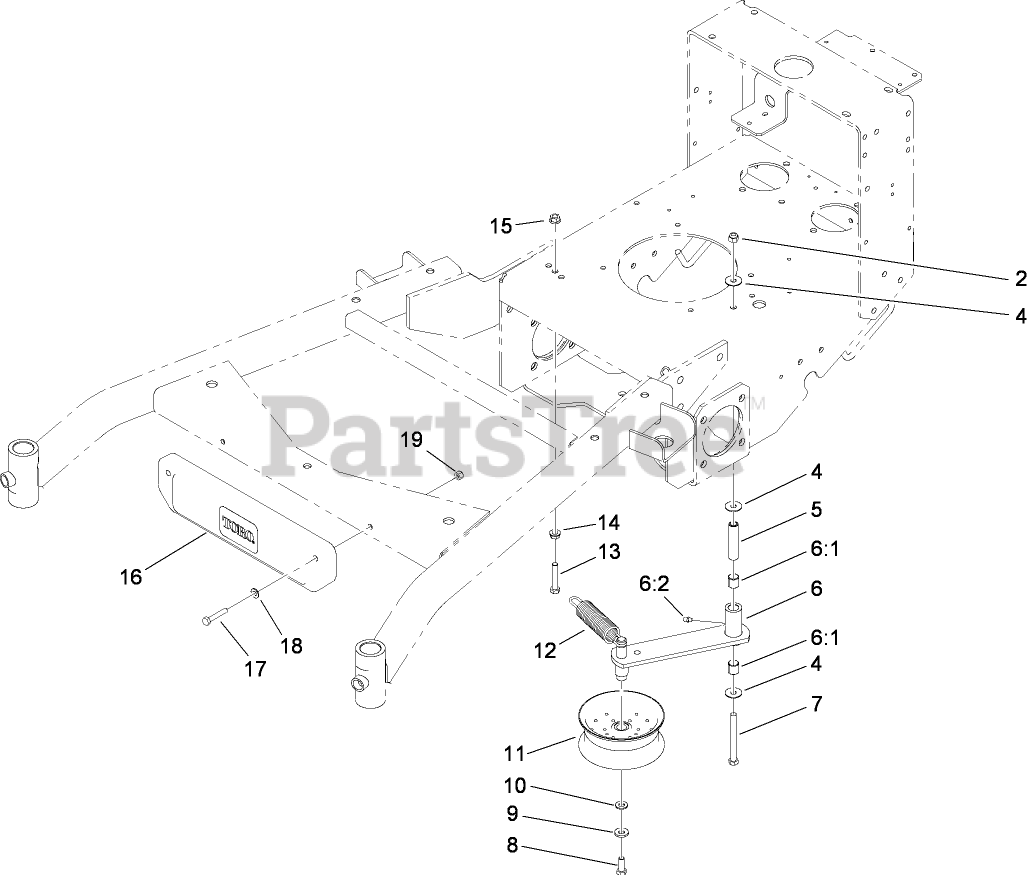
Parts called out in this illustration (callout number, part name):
2	NUT-LOCK, NI
4	WASHER
5	TUBE-IDLER
6	IDLER ARM ASM
6:1	SLEEVE-BEARING
6:2	FITTING-GREASE
7	SCREW-HH
8	SCREW-HH
9	WASHER-BELLEVILLE
10	WASHER-FLAT
11	PULLEY-IDLER
12	SPRING-EXTENSION
13	SCREW-HH
14	NUT-HHF, WHIZ
15	NUT-HF
16	WEIGHT-CAST
17	SCREW-HH
18	WASHER-PLAIN
19	NUT-LOCK, NI
